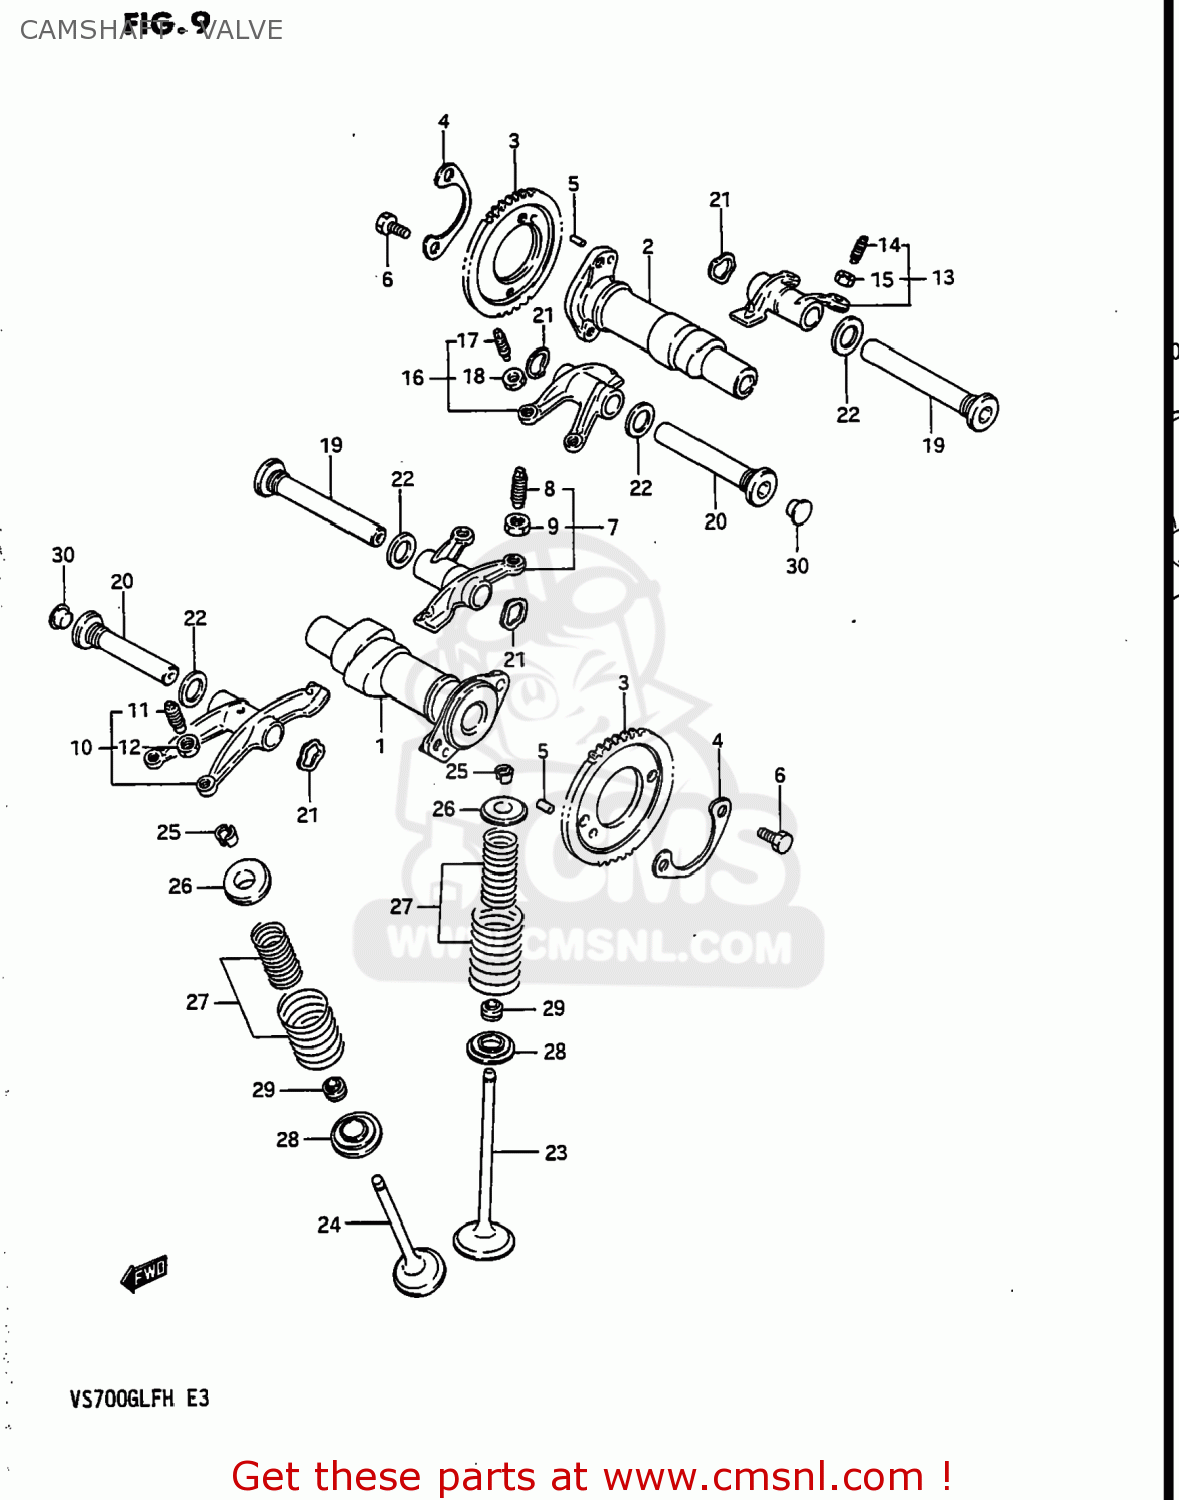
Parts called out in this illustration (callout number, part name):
1	CAMSHAFT
2	CAMSHAFT
3	SPROCKET,CAMSHAFT(NT:42)
4	WASHER,CAM CHAIN SPROCKET
5	PIN
6	BOLT(6X12.5)
7	ARM,INTAKE VALVE ROCKER FR
8	SCREW,TAPPET ADJUSTING
9	NUT,ADJUSTING SCREW
10	ARM,EXHAUST VALVE ROCKER FR
11	SCREW,TAPPET ADJUSTING
12	NUT,ADJUSTING SCREW
13	ARM,INTAKE VALVE ROCKER RR
14	SCREW,TAPPET ADJUSTING
15	NUT,ADJUSTING SCREW
16	ARM,EXHAUST VALVE ROCKER RR
17	SCREW,TAPPET ADJUSTING
18	NUT,ADJUSTING SCREW
19	SHAFT,VALVE ROCKER
20	SHAFT,VALVE ROCKER ARM
21	WASHER
22	GASKET(14X19.2X2) (NAS)
23	VALVE,INTAKE
24	VALVE,EXHAUST
25	COTTER,VALVE
26	RETAINER,VALVE SPRING
27	SPRING SET,VALVE
28	SEAT,VALVE SPRING
29	OIL SEAL
30	CAP(OD:12)
